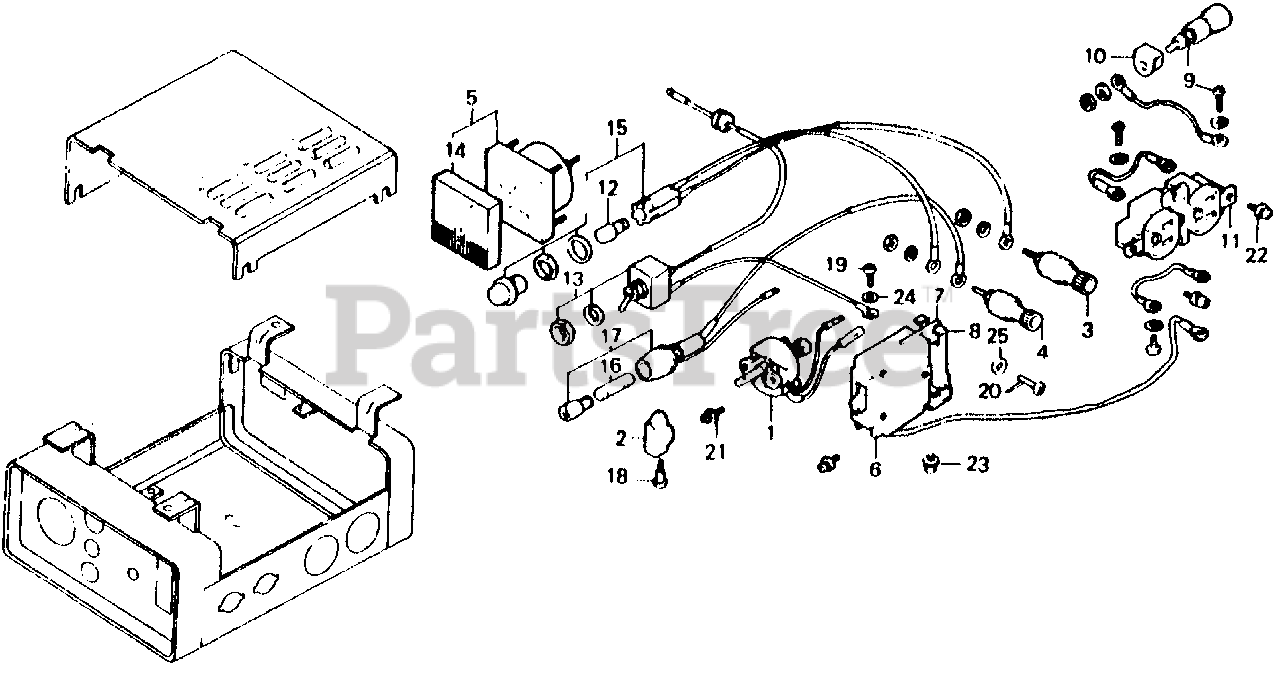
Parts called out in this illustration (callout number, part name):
1	RESISTOR, VARIABLE
2	KNOB, ADJUSTING
3	TERMINAL, D.C. OUT (+)
4	TERMINAL ASSY. B
4	TERMINAL, D.C. OUT (-)
5	VOLTMETER ASSY. (150V SCALE)
6	BREAKER ASSY., CIRCUIT
6	BREAKER, CIRCUIT (21A)
7	TERMINAL, BREAKER
8	SUPPORT, BREAKER (NOT AVAILABLE)
9	TERMINAL ASSY., GROUND
9	TERMINAL ASSY., GROUND (NOT AVAILABLE)
10	PLATE, GROUND
11	RECEPTACLE (15A 125V)
11	RECEPTACLE (15A-125V)
12	BULB (24V2W)
13	SWITCH ASSY., ENGINE (NOT AVAILABLE)
14	LENS, METER
15	SOCKET ASSY., PILOT LAMP (NOT AVAILABLE)
16	FUSE (15A)
17	HOLDER ASSY., FUSE
18	BOLT, KNOB (NOT AVAILABLE)
19	SCREW, PAN (4X8)
20	SCREW, PAN (5X10)
21	SCREW-WASHER (3X6)
22	SCREW-WASHER (4X12)
23	SCREW-WASHER (5X8)
24	WASHER, SPRING (4MM)
25	WASHER, SPRING (5MM)
